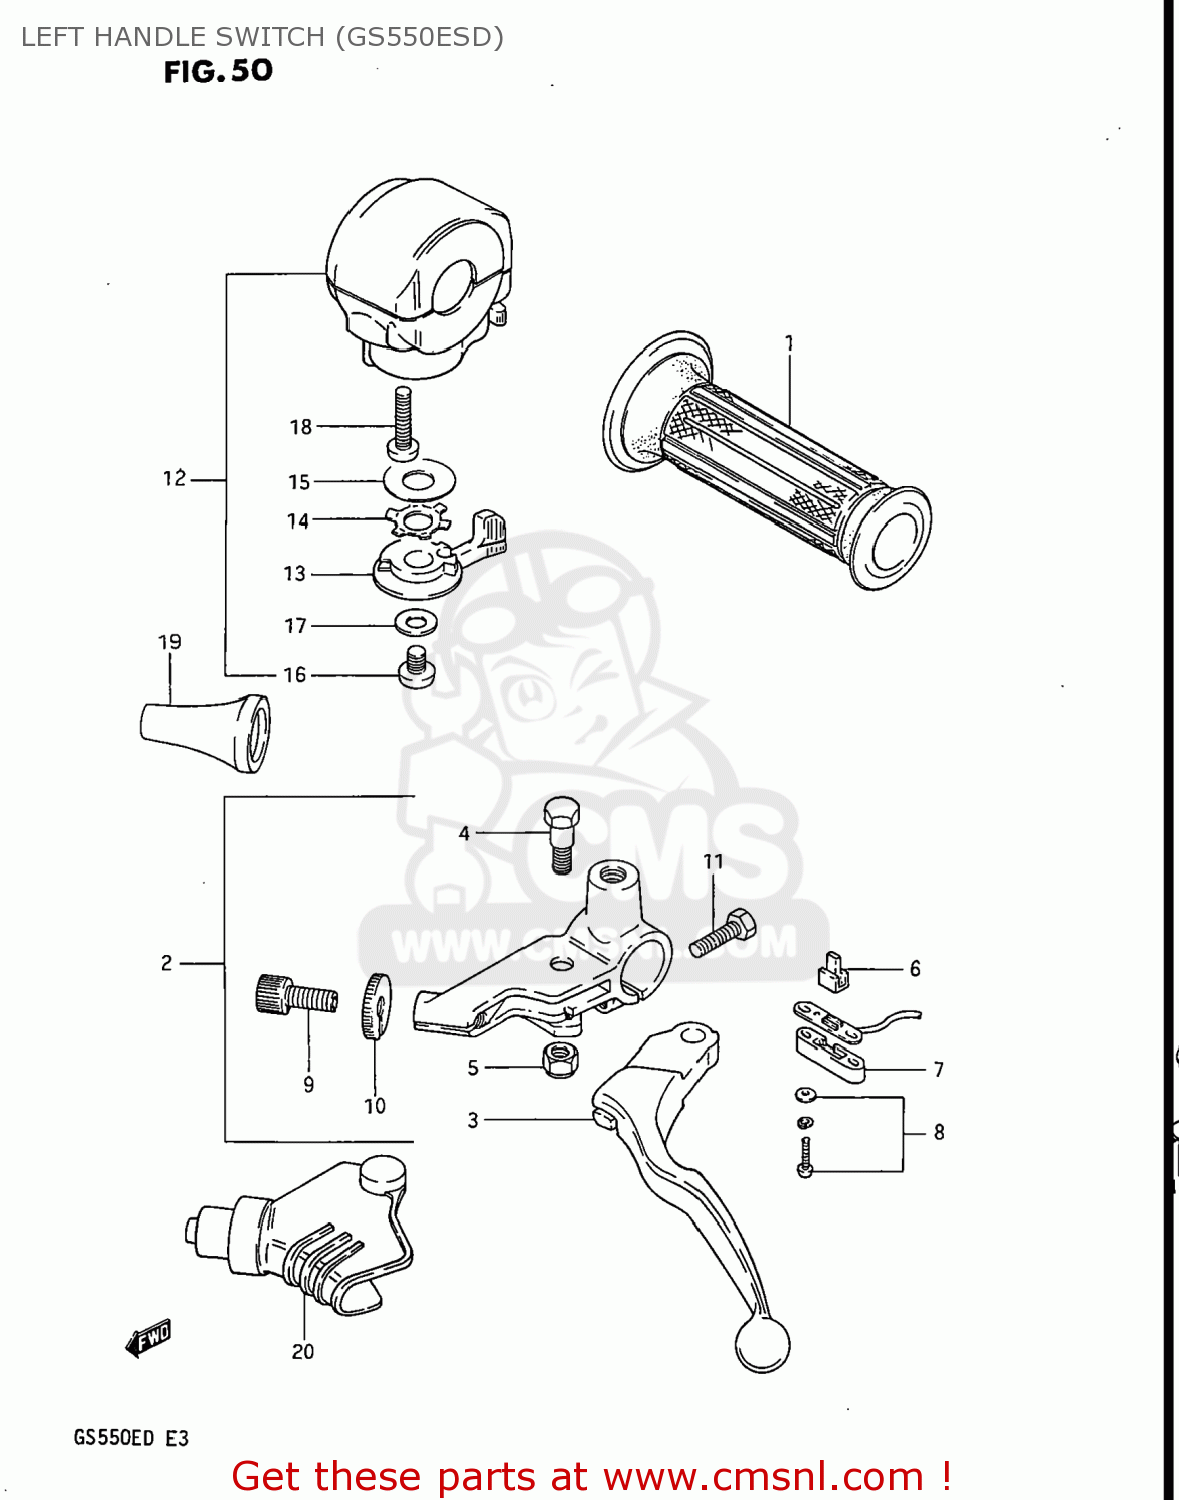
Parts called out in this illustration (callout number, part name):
1	GRIP,L
2	CLUTCH LEVER & SWITCH ASSY
3	LEVER,CLUTCH
4	BOLT,LEVER PIVOT
5	NUT 6MM
6	CONTACT,SWITCH
7	COVER,FR BK TERMINAL BASE
8	SCREW
9	ADJUSTER,CABLE
10	NUT,CABLE ADJUSTER
11	BOLT,CLUTCH LEVER HOLDER
12	SWITCH ASSEMBLY,HANDLE,LEFT
13	LEVER,STARTER
14	WASHER
15	WASHER
16	SCREW
17	WASHER 6MM
18	SCREW
19	BOOT,CLUTCH CABLE
20	COVER,CLUTCH LEVER
